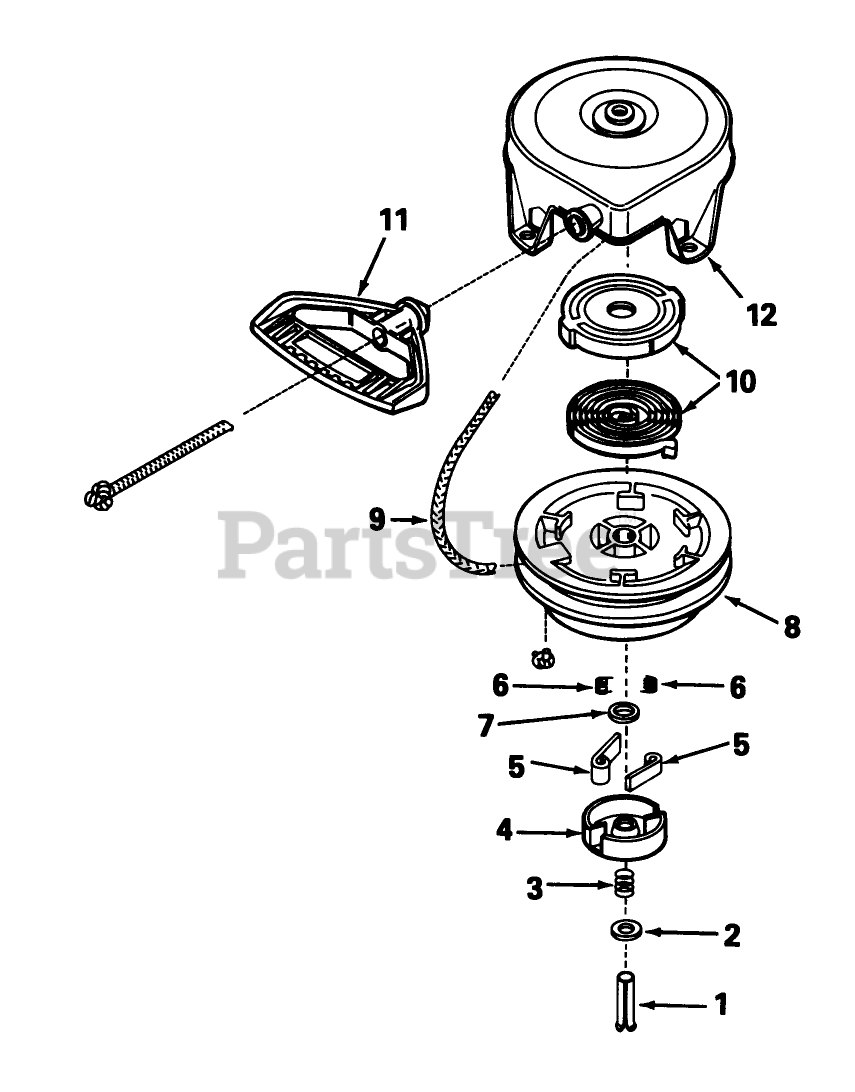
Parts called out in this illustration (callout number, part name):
1	Pin Spring
2	Washer
3	Brake Spring
4	Retainer
5	Dog-Starter
6	Spring-Dog
7	Washer
8	Pulley
9	Rope-Starter
10	Spring Keeper Assy.
11	Handle-Starter, Mitten Grip
12	Housing Assy., Starter
